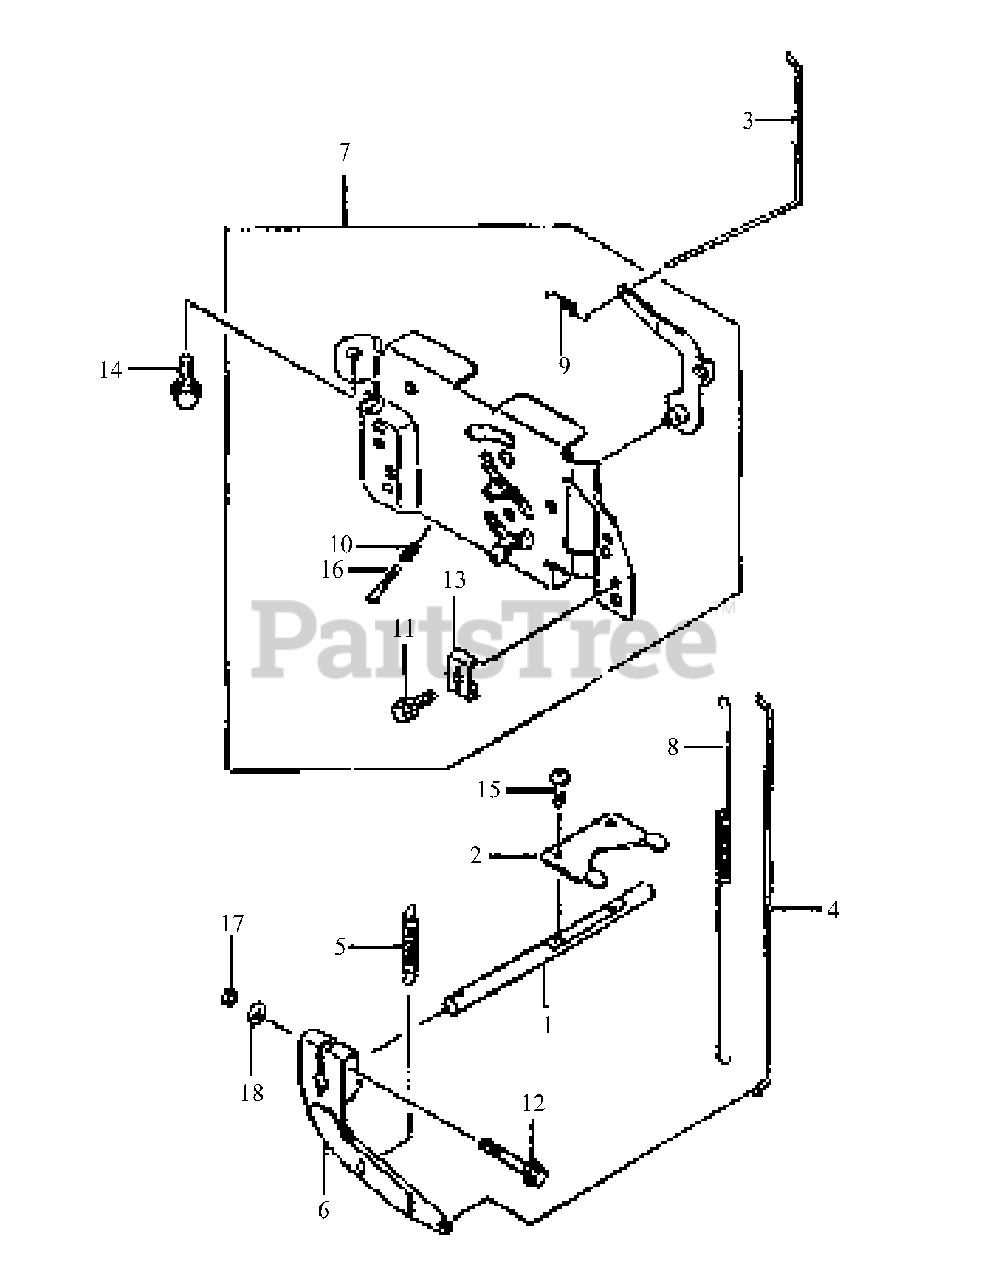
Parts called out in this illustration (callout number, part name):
1	Shaft
5	Spring, Governor
6	Arm, Governor
7	Panel, Control
9	Spring
14	Bolt, Flange
18	Washer, Plain
